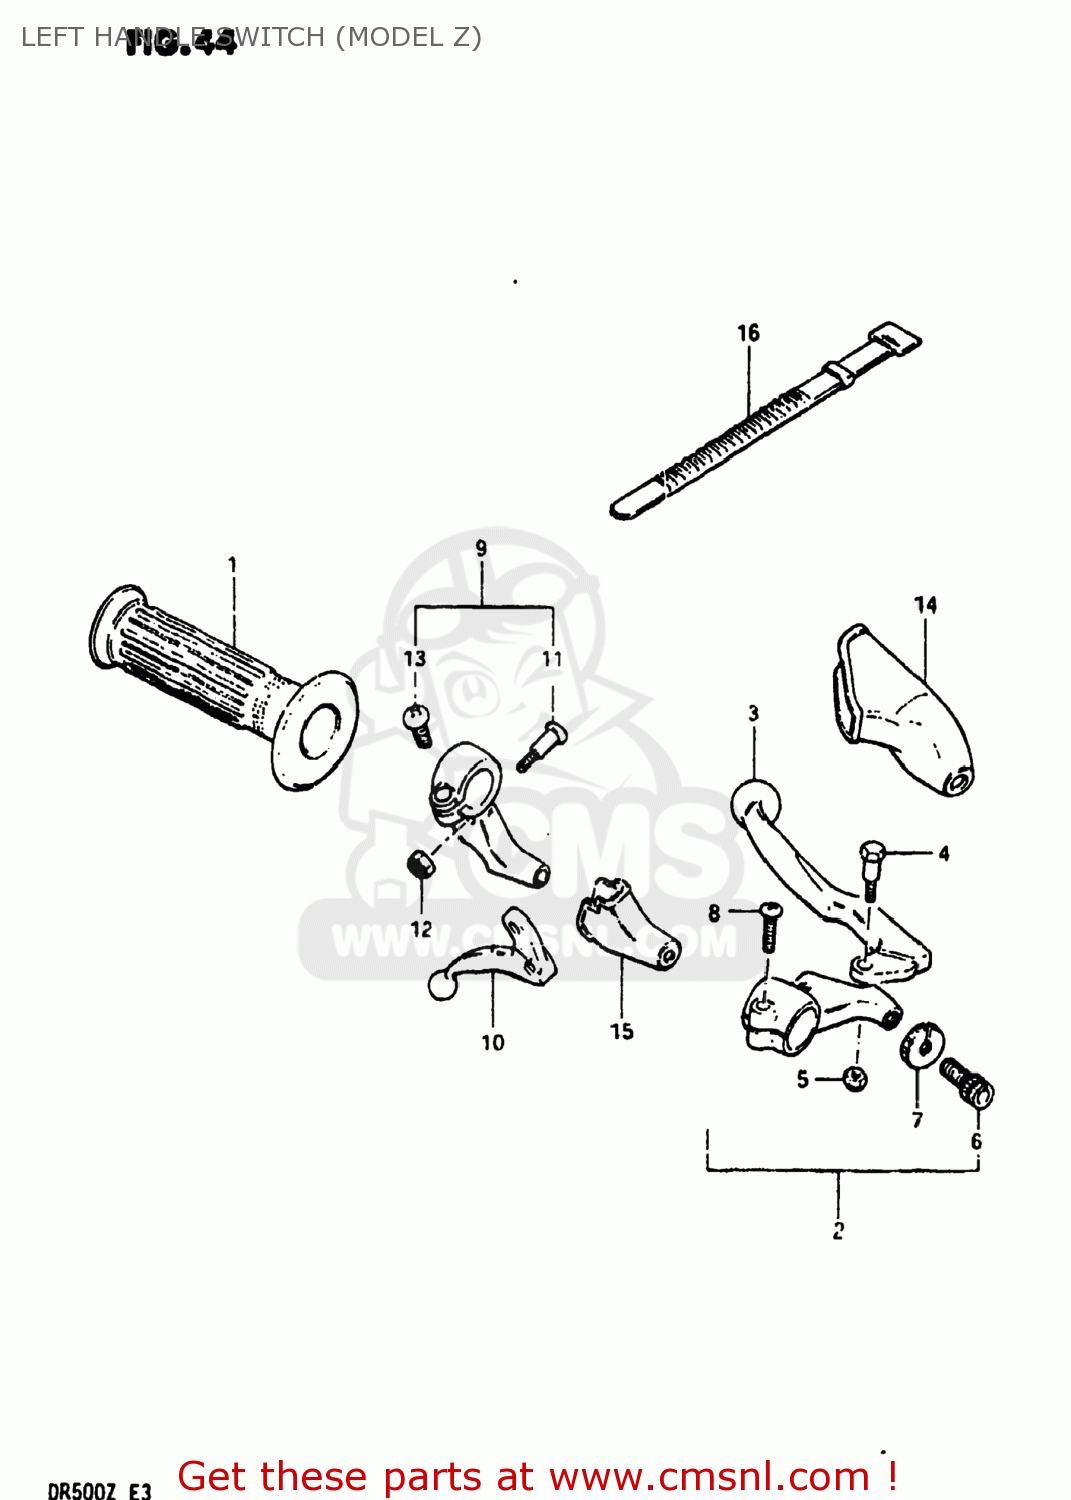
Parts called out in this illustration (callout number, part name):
1	GRIP,L
2	LEVER ASSEMBLY,CLUTCH
3	LEVER,CLUTCH
4	BOLT,LEVER
5	NUT 6MM
6	ADJUSTER,CABLE
7	NUT,CABLE ADJUSTER
8	SCREW
9	LEVER ASSEMBLY,DECOMPRESSION
10	LEVER,DECOMP
11	BOLT,LEVER
12	NUT,LEVER BOLT
13	SCREW
14	COVER,CLUTCH LEVER
15	COVER,DECOMP LEVER DUST
16	CLAMP
